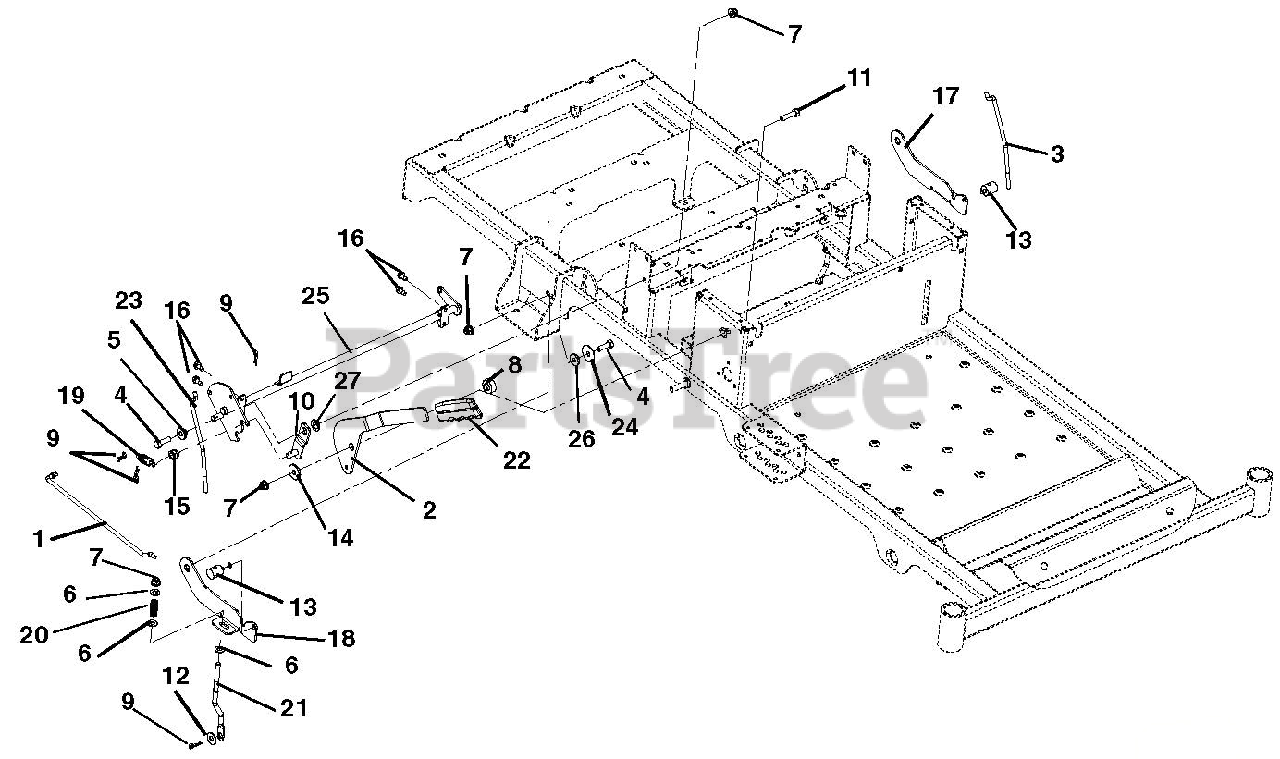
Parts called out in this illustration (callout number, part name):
1	LINK, BRAKE HANDLE
2	HANDLE, PARKING BRAKE
3	LINK, NEUTRAL LH
4	@BLT-HEX .31-18X1.00 GR5 YWZC
5	BSHG-FLG .32X.500X.344X.880
6	@WSHR-FL-STL.344X.688X.065YWZC
7	@NUT-LK-NYL-FLG .31-18 YWZC
8	SPCR,BRAKE .32X.49X.192X1.00
9	PIN-HAIR INT .08X.18X1.18 YWZC
10	WELDMENT,DETENT ARM
11	@BLT-HEX .31-18X1.25 GR5 YWZC
12	@WSHR-FL-STL.38X.875X.083 YWZC
13	TRUNION, 1/4-20
14	WSHR-FL-STL .344X1.125X.135
16	@SCR-TAP .25-20X.50 HWH TR YWZ
17	LATCH,LH NETURAL
18	LATCH,RH NETURAL
19	SG-TENS .072X.565X1.87
20	SPRING, COMPRESSION
21	LINK, BRAKE COG
22	GRIP, PARKING BRAKE (YELLOW)
23	LINK, NEUTRAL RH
24	WSHR-FL-STL .347X1.254X.048YWZ
25	WELDMENT, BRAKE SHAFT
26	BSHG, FLG .325X.499X.26X.88
27	WSHR-FL-STL .52X.827X.062 YWZC
